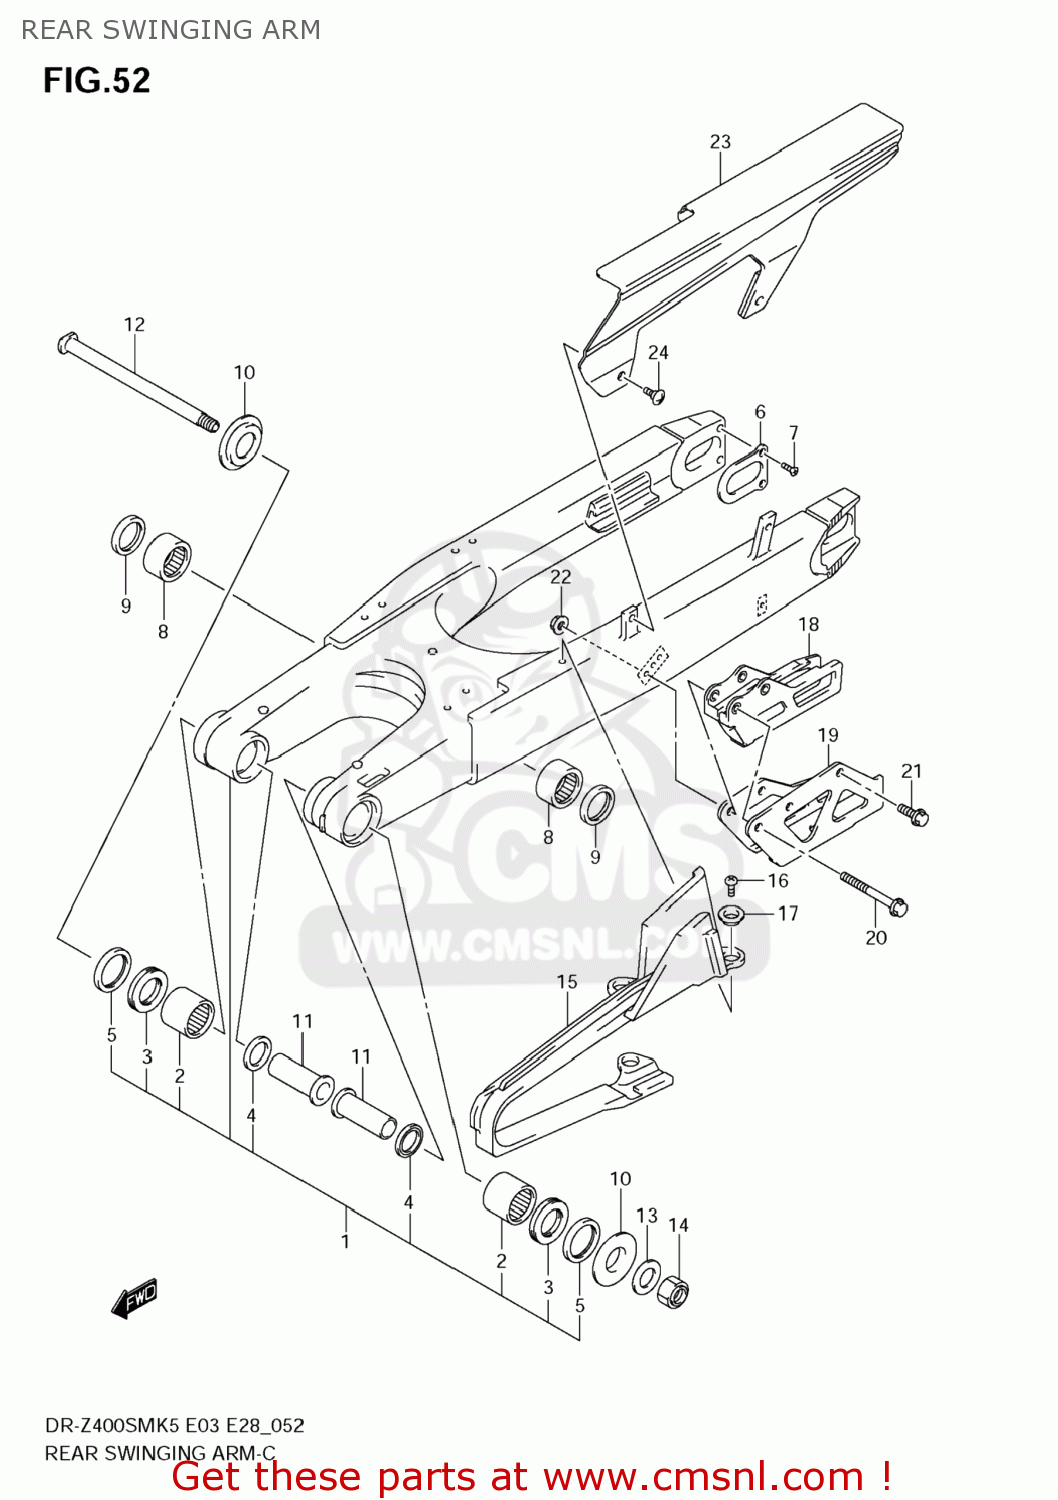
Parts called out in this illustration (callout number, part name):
1	SWINGINGARM ASSY,RR
2	BEARING(22X29X30)
3	BEARING(22X35X2)
4	SEAL,OIL(22X29X4)
5	SEAL,RR SWGARM PIVOT OUTER
6	PLATE,SWING ARM RR
7	SCREW
8	BEARING(20X27X15)
9	SEAL,CUSHION LEVER DUST
10	SPACER,SWINGINGARM PIVOT OUTER
11	SPACER,SWGARM PIVOT INNER
12	SHAFT,RR SWINGINGARM PIVOT
13	WASHER
14	NUT
15	BUFFER,CHAIN TOUCH DEFENSE
16	SCREW
17	WASHER
18	GUIDE,CHAIN
19	PLATE,CHAIN GUIDE
20	BOLT(6X50)
21	BOLT(6X12)
22	NUT
23	CASE,CHAIN
24	SCREW(6X16)
